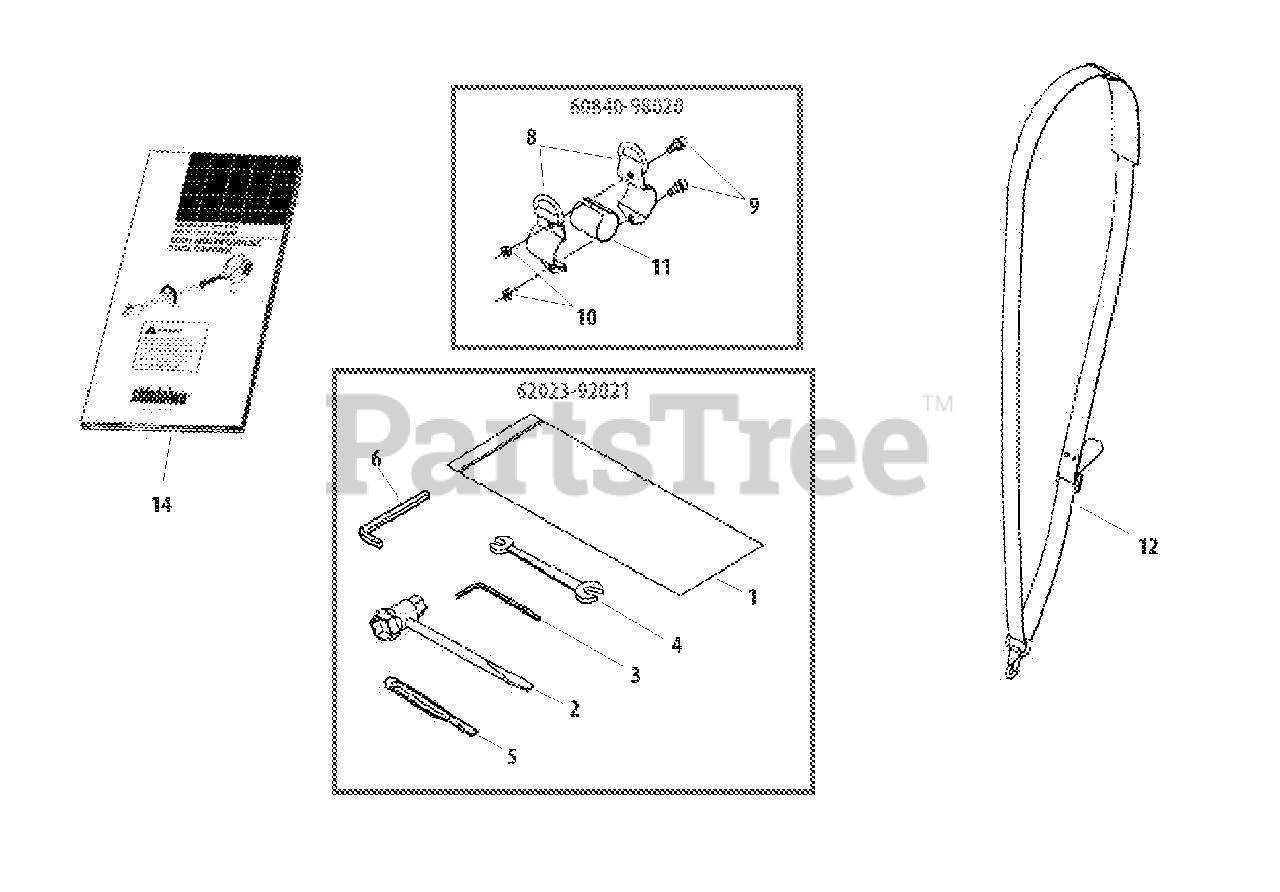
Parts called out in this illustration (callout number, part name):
1	BAG, TOOL
2	T-WRENCH - 13X19mm
3	HEX KEY - 4mm
4	SPANNER - 8X10mm
5	SCREWDRIVER - PLASTIC
6	HEX KEY - 3mm
8	HANGER
9	SCREW - 5X12
10	NUT - 5
11	SHIM
12	STRAP ASSY
14	OWNER'S MANUAL
60840-98020	HANGER ASSY
62023-92021	TOOL KIT
